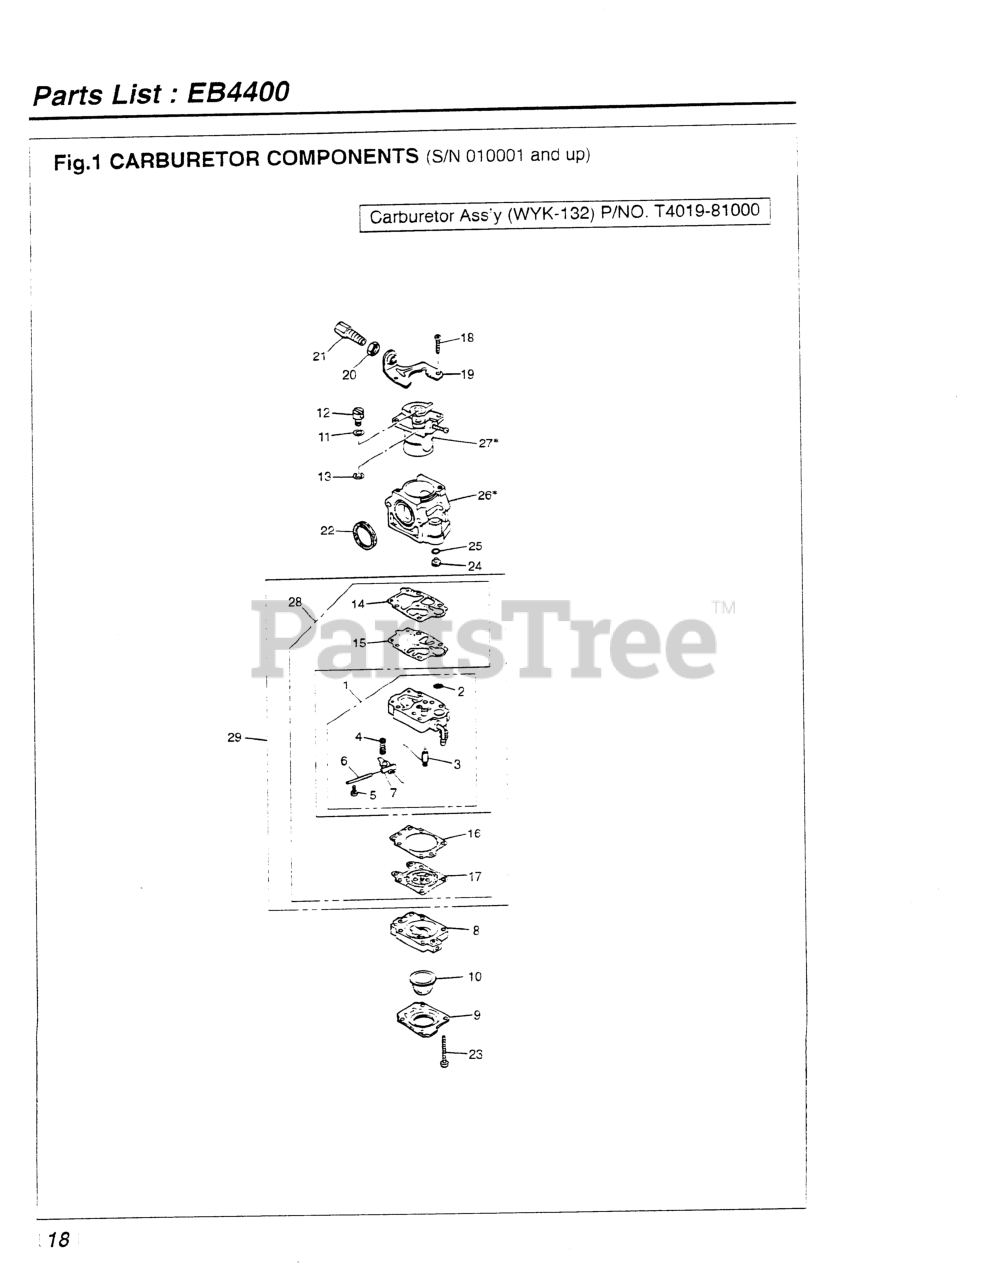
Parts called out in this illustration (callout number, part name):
1	BODY, PUMP
2	SCREEN
3	VALVE, INLET
5	SCREW
6	PIN
7	LEVER
8	BODY, PURGE
9	COVER, PUMP
10	PUMP, PRIMING
11	WASHER
12	SWIVEL
13	RING
14	GASKET
15	DIAPHRAGM
16	GASKET
17	DIAPHRAGM
18	SCREW
20	NUT, CABLE ADJUSTER
21	SCREW, CABLE ADJUSTER
22	RING, PACKING
23	SCREW
25	RING, O
26	CARBURETOR
27	CARBURETOR
